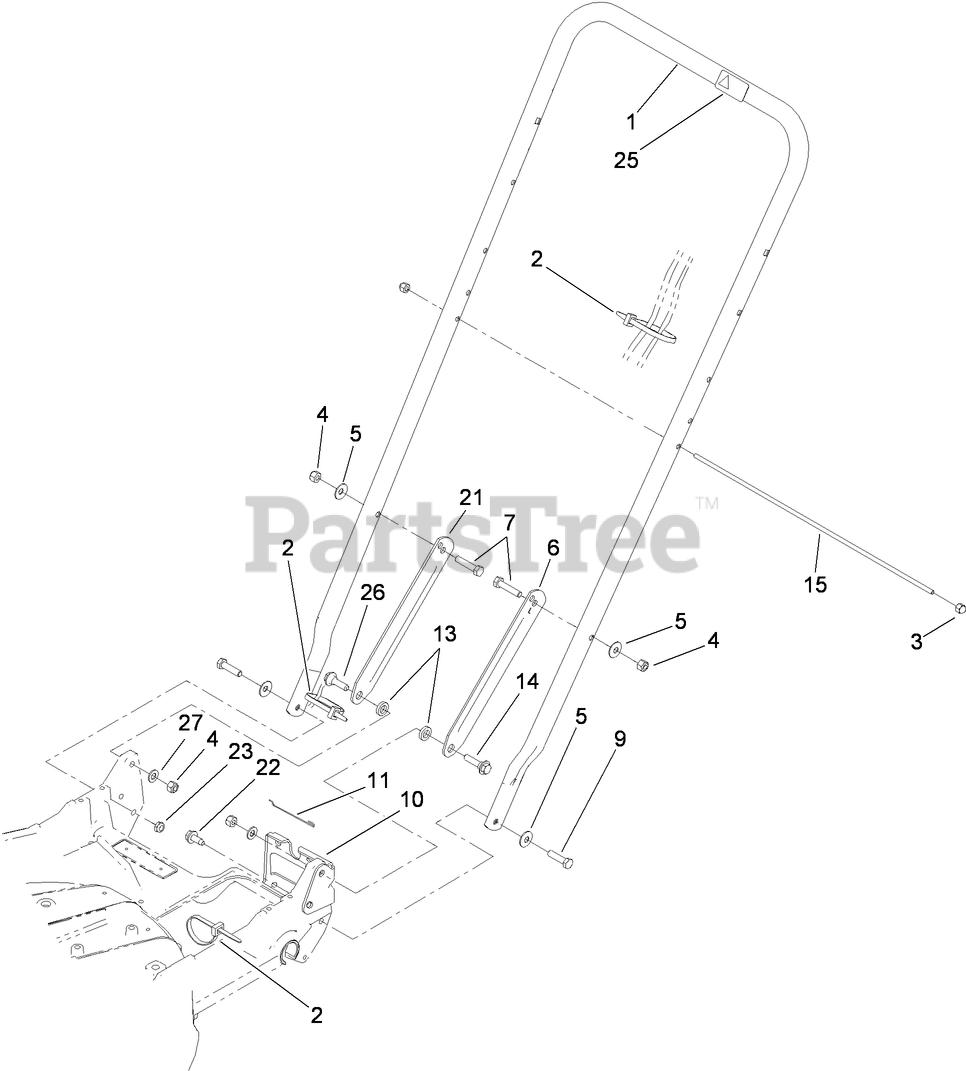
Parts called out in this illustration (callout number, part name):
2	TIE-CABLE
3	NUT-CAP
4	NUT-LOCK, NI
5	WASHER-BELLEVILLE
6	LATCH-HANDLE, LH
7	SCREW-HH
9	SCREW-HH
10	BRACKET-ADJUSTMENT, TRACTION
11	RETAINER-CABLE
13	SPACER
14	SCREW-SHOULDER
15	ROD-SUPPORT, BAG
21	LATCH-HANDLE, RH
22	SCREW-HWHTF
23	NUT-LOCK, NI
25	DECAL-PROTECTION, EAR
26	SCREW-SHOULDER
27	WASHER-PLAIN
